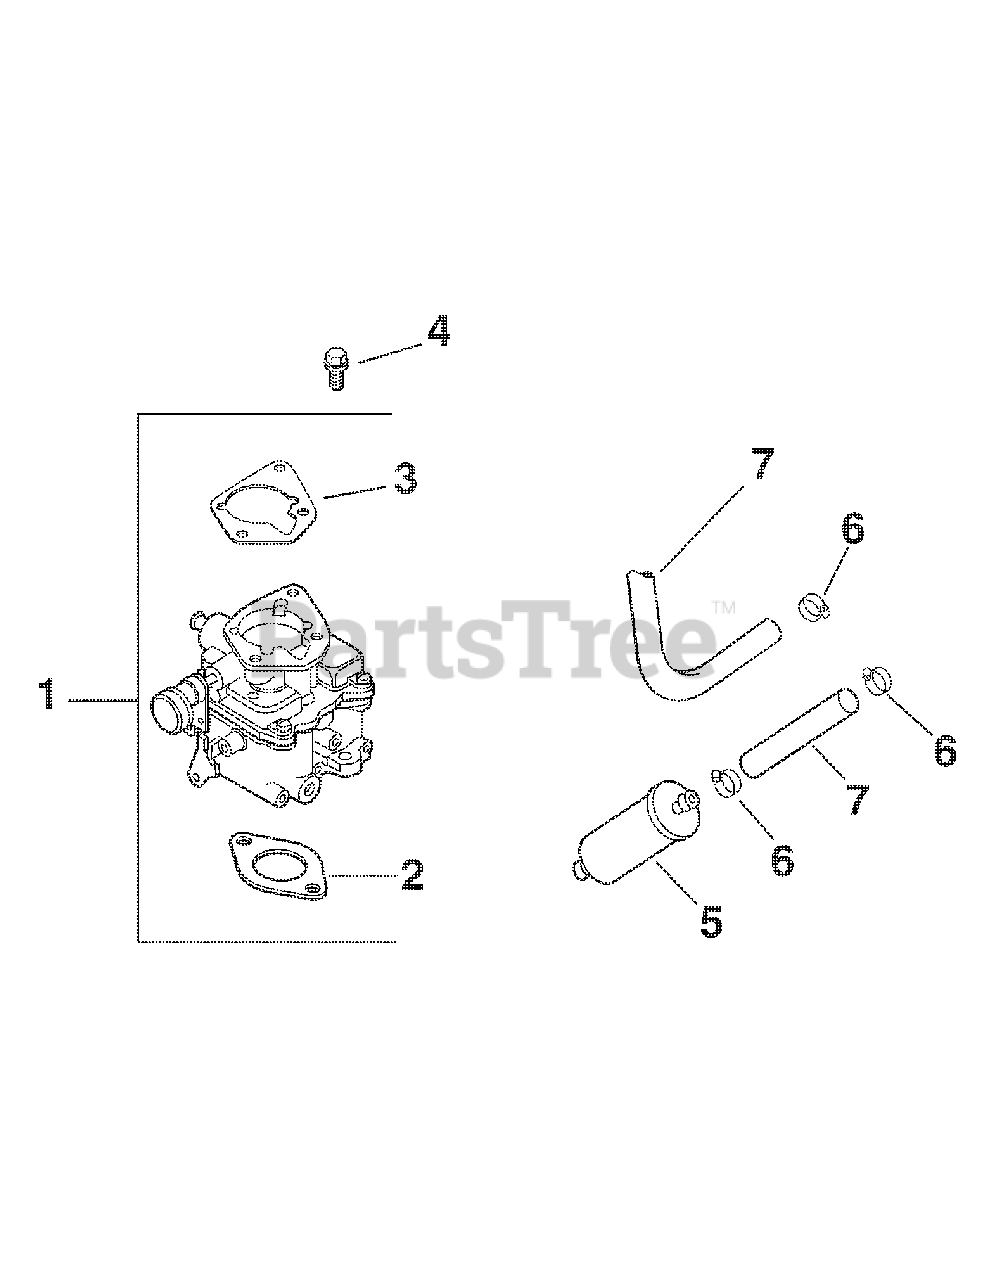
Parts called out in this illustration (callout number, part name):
1	Kit,carburetor w/gasket (Includes 2, 3)
2	Gasket, carburetor
3	Gasket, air cleaner base
4	Screw, hex. Flange M6x1.0x25 (2)
5	Filter, fuel
6	Clamp, hose (4)
7	Line, fuel 24" - cut to
